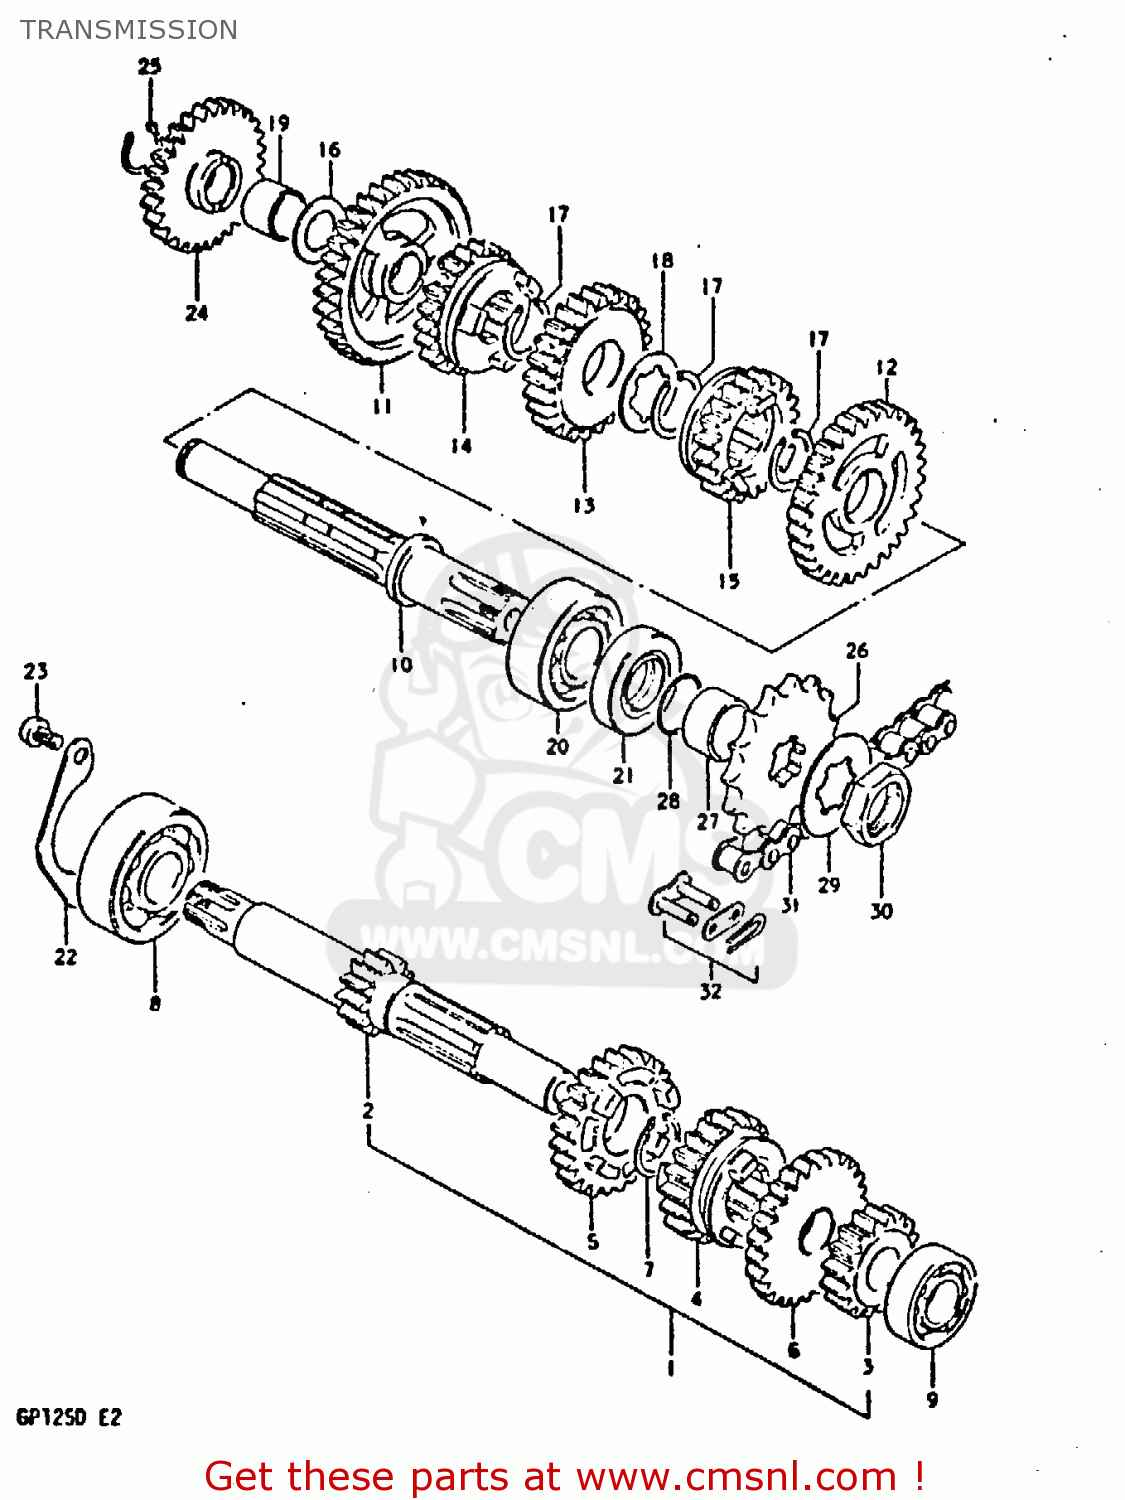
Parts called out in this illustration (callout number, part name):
1	COUNTERSHAFT
2	COUNTER SHAFT (NT:11)
3	GEAR,SECOND DRIVE
4	GEAR, 3RD DRIVE (NT:20)
5	GEAR, 4TH DRIVE (NT:23)
6	GEAR, 5TH DRIVE (NT:25)
7	CIRCLIP
8	Bearing
9	BEARING
10	SHAFT, DRIVE
11	GEAR,1ST DRIVEN
12	GEAR, 2ND DRIVEN (NT:29)
13	GEAR, 3RD DRIVEN (NT:25)
14	GEAR, 4TH DRIVEN (NT:22)
15	GEAR, 5TH DRIVEN (NT:20)
16	WASHER,THRUST
17	CIRCLIP
18	WASHER
19	BUSH
20	Bearing
21	SEAL,OIL(25X40X7)
22	RETAINER,CNTR SHAFT BEARING
23	SCREW 6X12
24	GEAR,KICK STARTER IDLE
25	CIRCLIP,15MM
26	SPROCKET,ENGINE(NT:15)
27	SPACER(20X25X12.5)
28	O RING(D:1,ID:19.5)
29	WASHER,LOCK
30	NUT
31	CHAIN ASSEMBLY,DRIVE
32	JOINT ASSEMBLY,CHAIN
